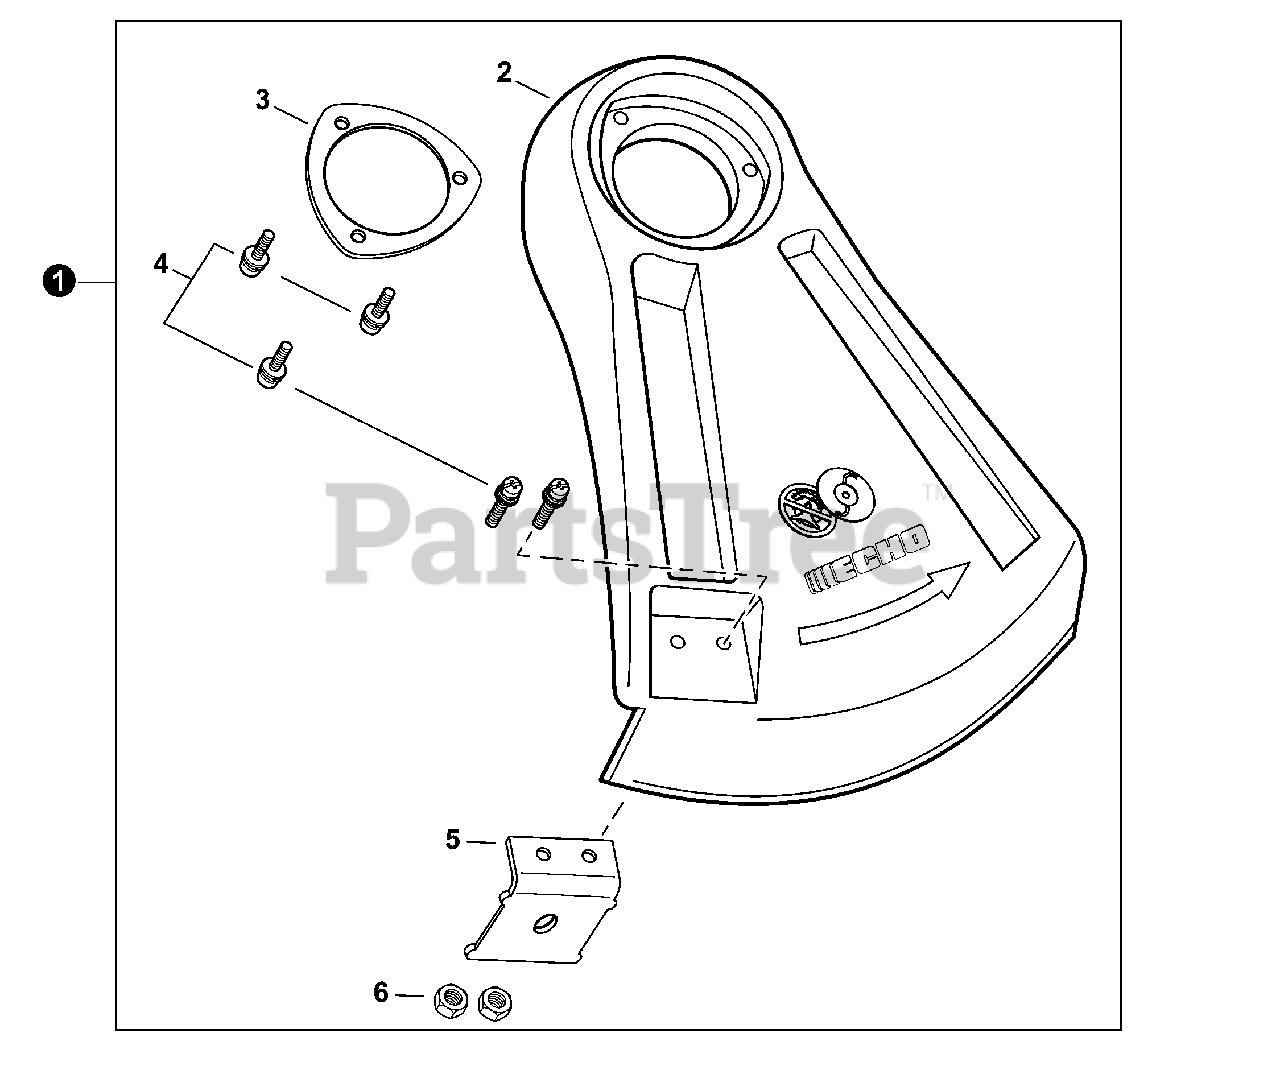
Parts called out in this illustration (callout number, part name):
1	DEBRIS SHIELD KIT
2	SHIELD, DEBRIS PLASTIC
3	PLATE, SHIELD Ø49.5 MM
4	SCREW 5×16
5	CUTTER, LINE
6	NUT M5
